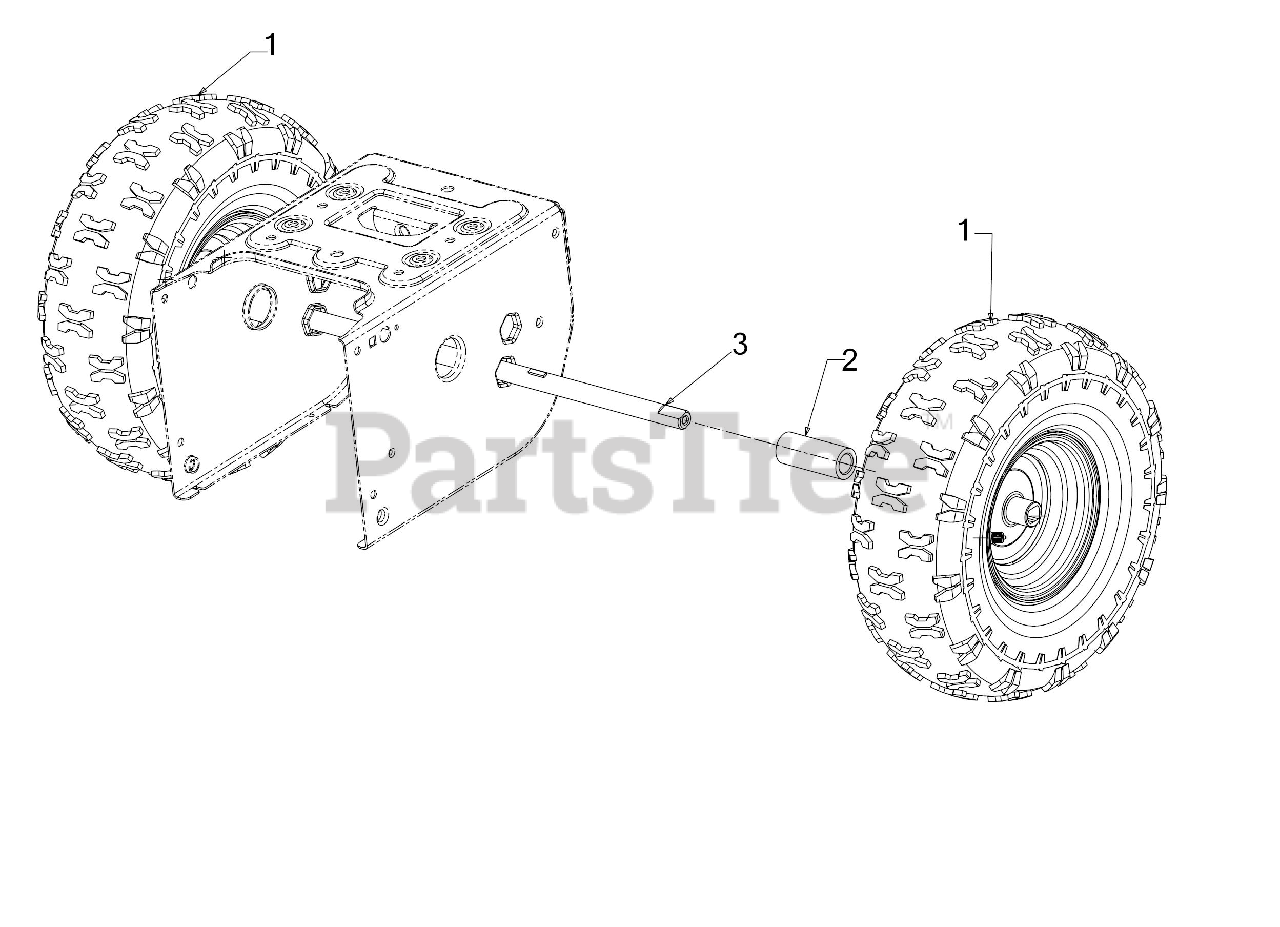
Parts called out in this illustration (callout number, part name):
1	WHEEL ASSEMBLY (15 x 5)
2	WHEEL SPACER 1.25ODX.75X3.00
3	WHEEL AXLE SHAFT .75 x 22"
